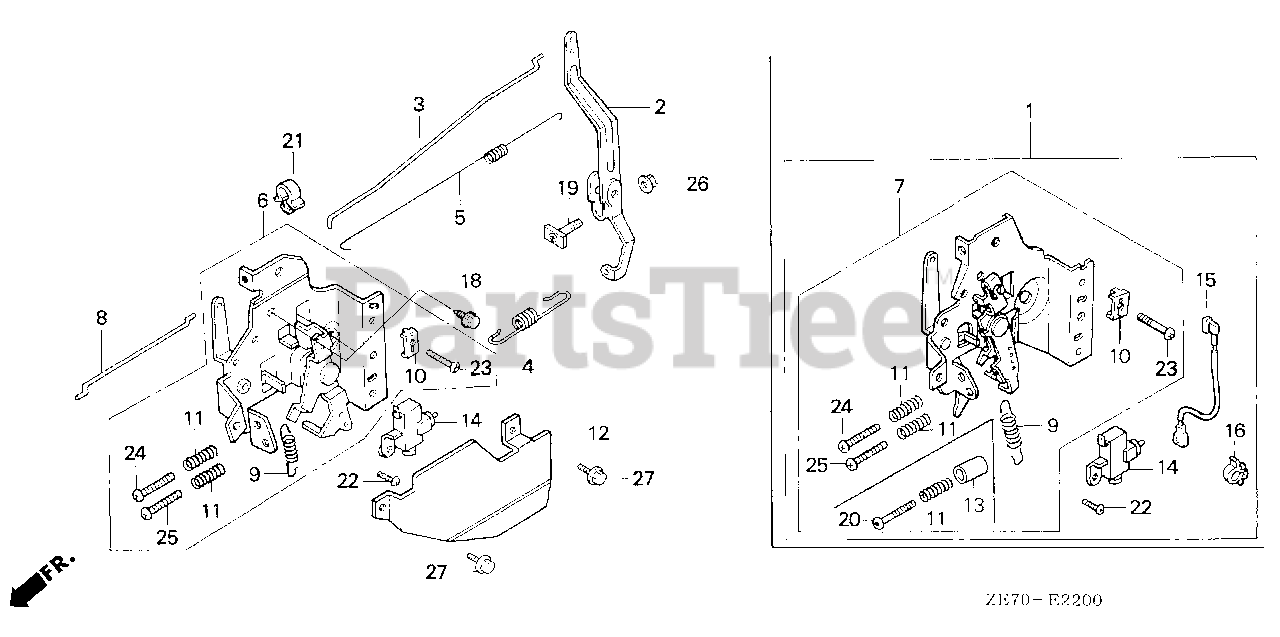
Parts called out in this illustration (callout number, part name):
2	ARM, GOVERNOR
3	ROD, GOVERNOR
4	SPRING, GOVERNOR
5	SPRING, THROTTLE RETURN
6	CONTROL ASSY.
8	ROD, CHOKE
9	SPRING, LEVER
10	HOLDER, CABLE
11	SPRING, CONTROL ADJUSTING
12	PROTECTOR, CONTROL
14	SWITCH ASSY., ENGINE STOP
18	BOLT, FLANGE (6X12) (CT200)
19	BOLT, GOVERNOR ARM
21	CLIP, WIRE HARNESS
22	SCREW, PAN (4X8)
23	SCREW, PAN (5X16)
24	SCREW, PAN (5X20)
25	SCREW, PAN (5X28)
26	NUT, FLANGE (6MM)
27	BOLT, FLANGE (6X10)
